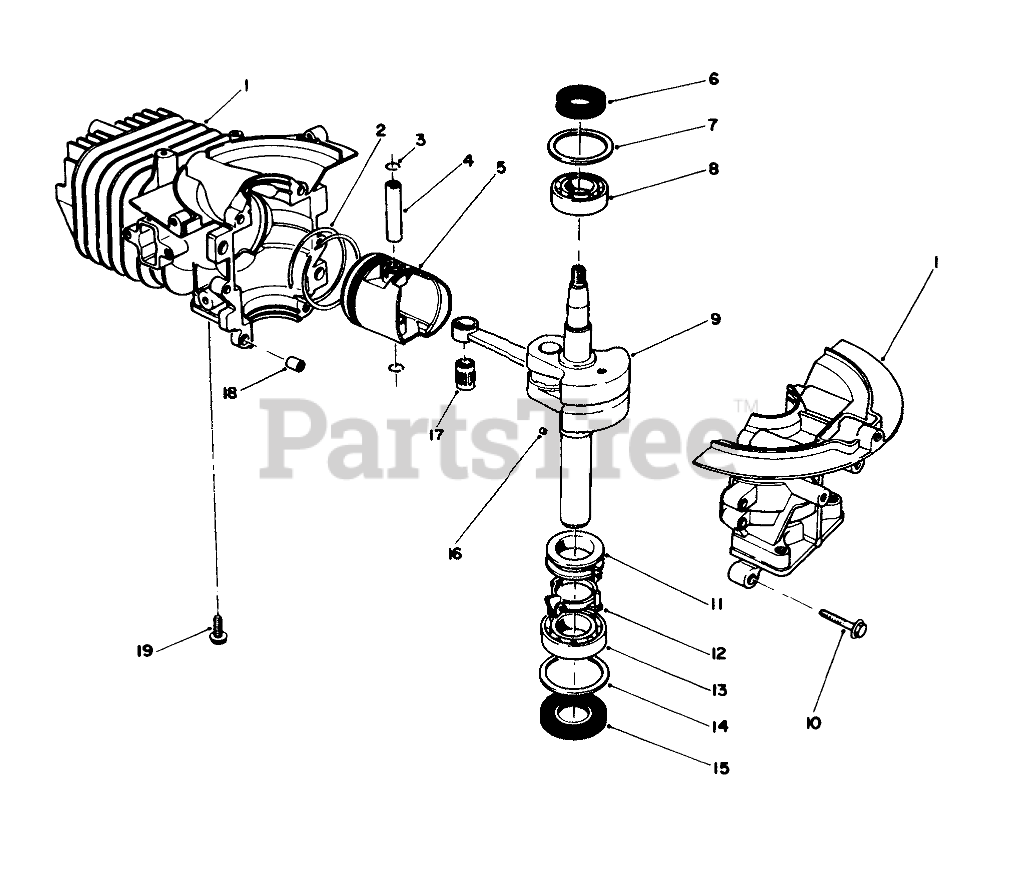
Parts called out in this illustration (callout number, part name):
1	CYLINDER/CRANKCASE
2	RING SET
4	HOUSING - CYL AIR, LH
5	Piston
6	OIL SEAL
7	WASHER-UPPER
8	BEARING-UPPER
9	CRANKSHAFT
11	SPACER
12	BRACKET
13	LOWER BRG
14	WASHER-LOWER
15	SEAL-OIL
17	BEARING
